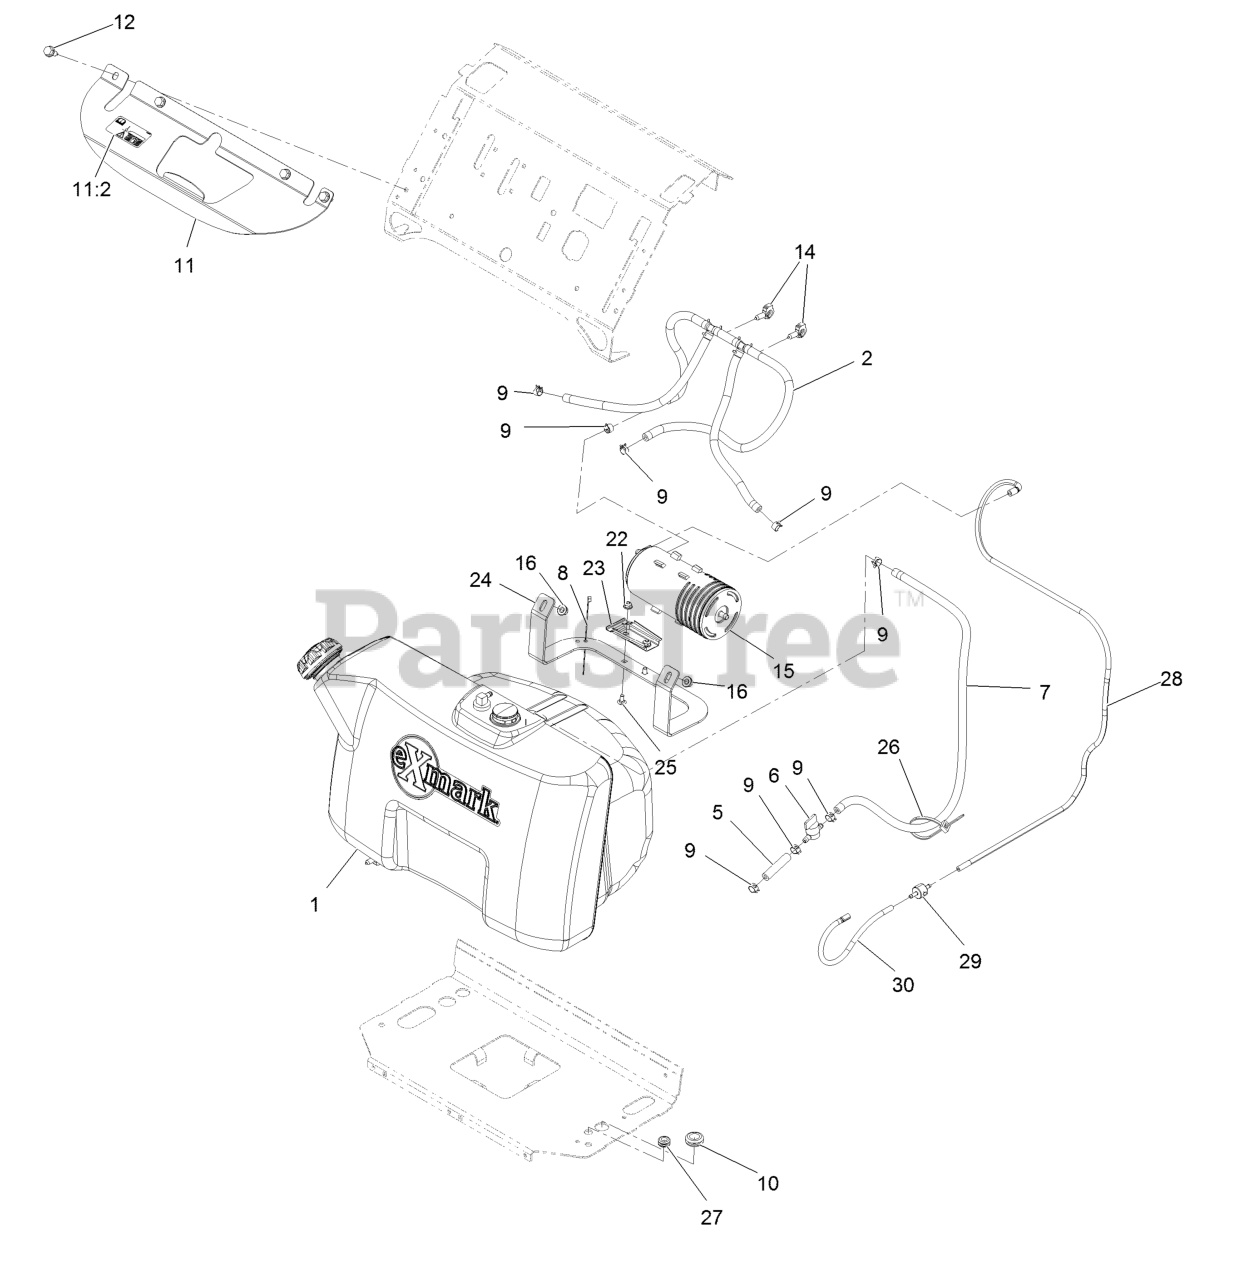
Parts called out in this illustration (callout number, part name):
1	Tank ASM-
2	Vent ASM
5	Hose-Fuel
6	Valve-Fuel
7	Hose-Fuel Line 32"
8	Tie-Cable 5 1/2 (Small)
9	Clamp-Hose
10	Grommet
11	Bracket-Tank
11:2	Decal-Fill, Fuel
12	Screw-HWH 5/16-18 X 3/4 Tf
14	Clip-Harness
15	Canister-Carbon, 800Cc
16	Nut-Nyloc 5/16-18 Flg
22	Nut-Nyloc 1/4-20 Flg
23	Bracket-Canister, Carbon
24	Bracket-Canister Mounting
25	Bolt-Carriage 1/4-20 X 1/2 Short Neck
26	Tie-Cable
27	Grommet
28	Hose, Formed
29	Valve-Check, Vacuum
30	Hose-Vent, Formed
